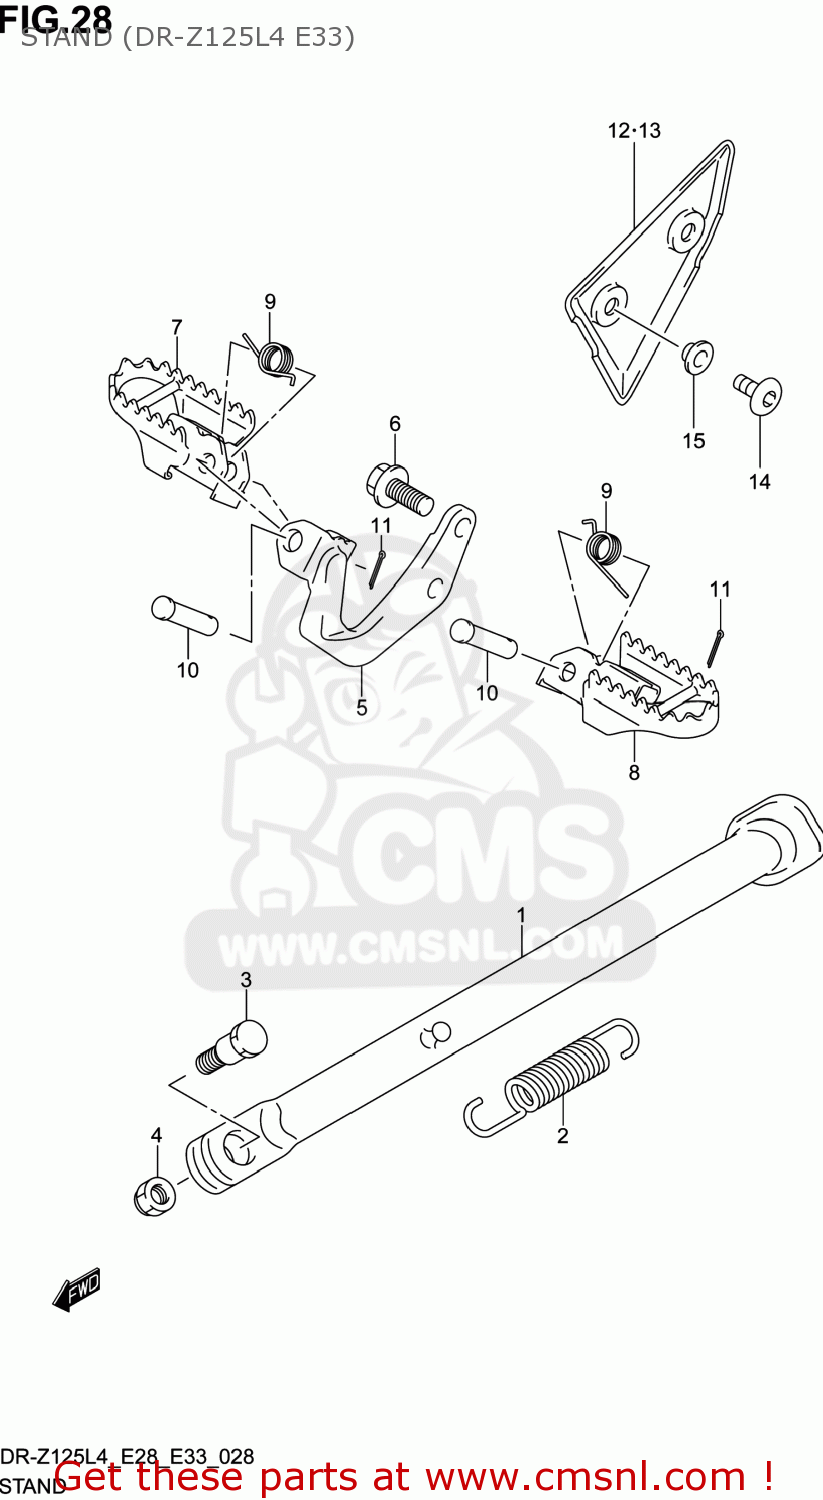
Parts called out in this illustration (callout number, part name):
1	STAND,PROP
2	SPRING
3	BOLT(10X33)
4	NUT,PROP STAND
5	BRACKET,FR FOOTREST,R
6	BOLT
7	FOOTREST,FR,R
8	FOOTREST,FR,L
9	SPRING
10	PIN
11	PIN
12	GUARD,FR FOOTREST,R
13	GUARD,FR FOOTREST,L
14	SCREW(6X12)
15	WASHER
